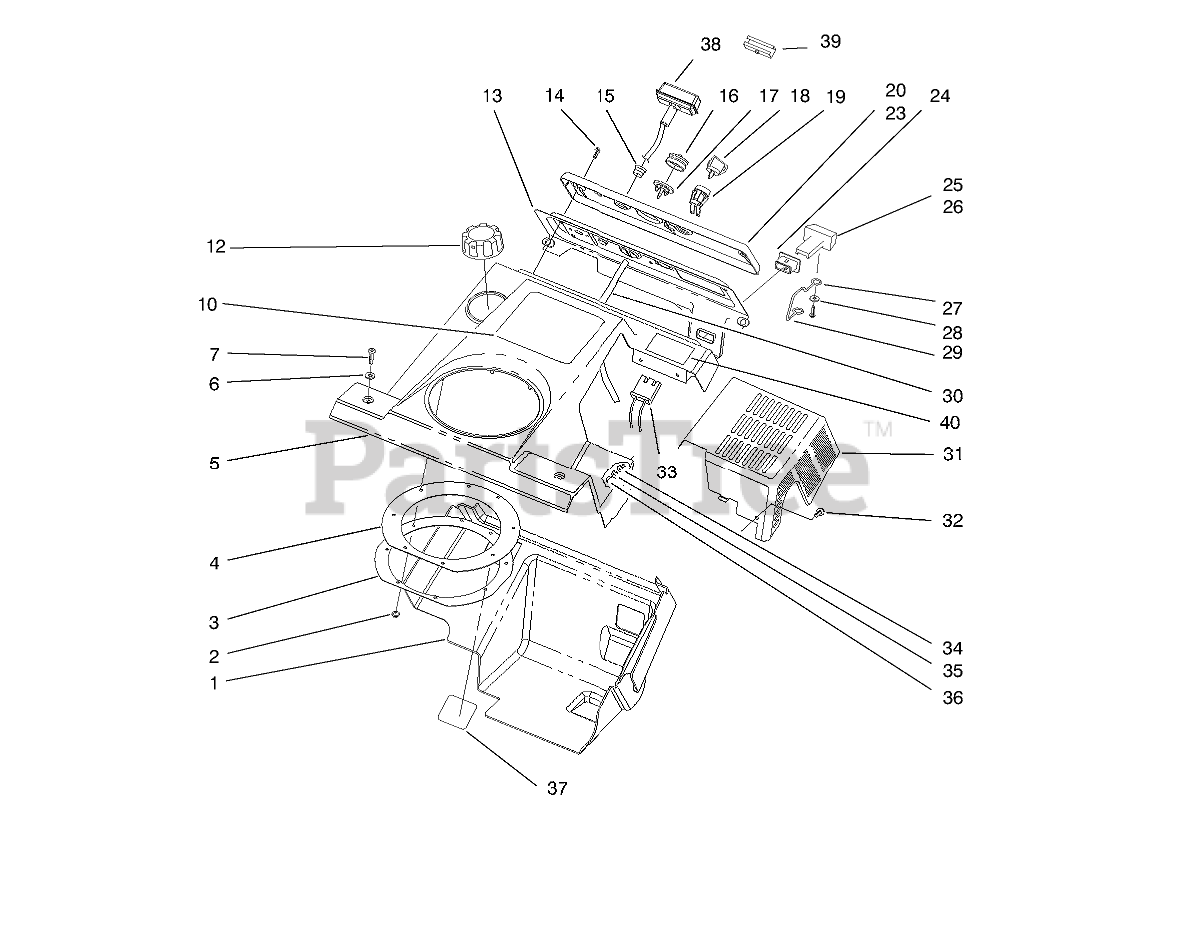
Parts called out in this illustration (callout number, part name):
1	SHROUD - LOWER
2	PALNUT
3	CHUTE SEAL RETAINER RED
4	SEAL-CHUTE
5	SHROUD - UPPER
6	WASHER-FLAT
7	SCREW-PPH
10	DECAL - CCR 2400 GTS E
12	CAP-FUEL ASM
13	Wa-Panel
14	SCREW-HWH
15	GUIDE-ROPE, STARTER
16	BULB-PRIMER
17	BODY-PRIMER
18	KEY-IGNITION
19	SWITCH
20	PLATE
23	Plate-Name
24	FITTING
25	CHOKE CONTROL
26	CONTROL-CHOKE
27	WASHER-PLAIN
28	SCREW-PPH
29	LINKAGE-CHOKE
30	HOSE-PRIMER
31	Shield-Heat
32	SCREW-SHH
33	CONNECTOR-BODY
34	WASHER
35	WASHER-FLAT
36	NUT-LOCK, NI
37	DECAL
38	HANDLE-START
39	CLIP-STARTER
40	DECAL
